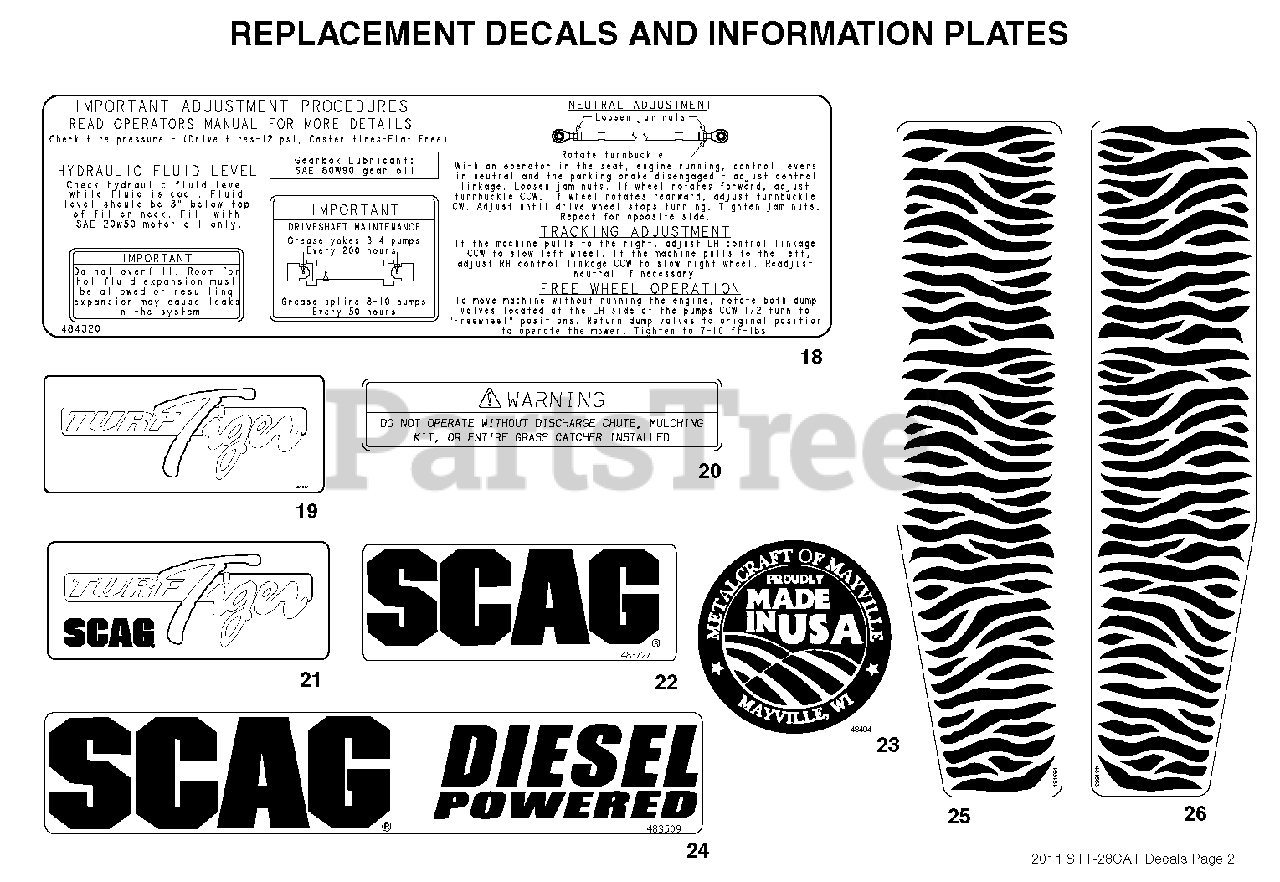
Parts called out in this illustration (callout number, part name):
18	Decal, Checks and Adjustments
19	Decal, Turf Tiger
20	Decal, Warning
21	Decal, Turf Tiger
22	Decal, Scag Logo
23	Decal, Metalcraft-Made In USA
24	Decal, Scag Diesel Powered
25	Decal, Stripes-RH
26	Decal, Stripes-LH
